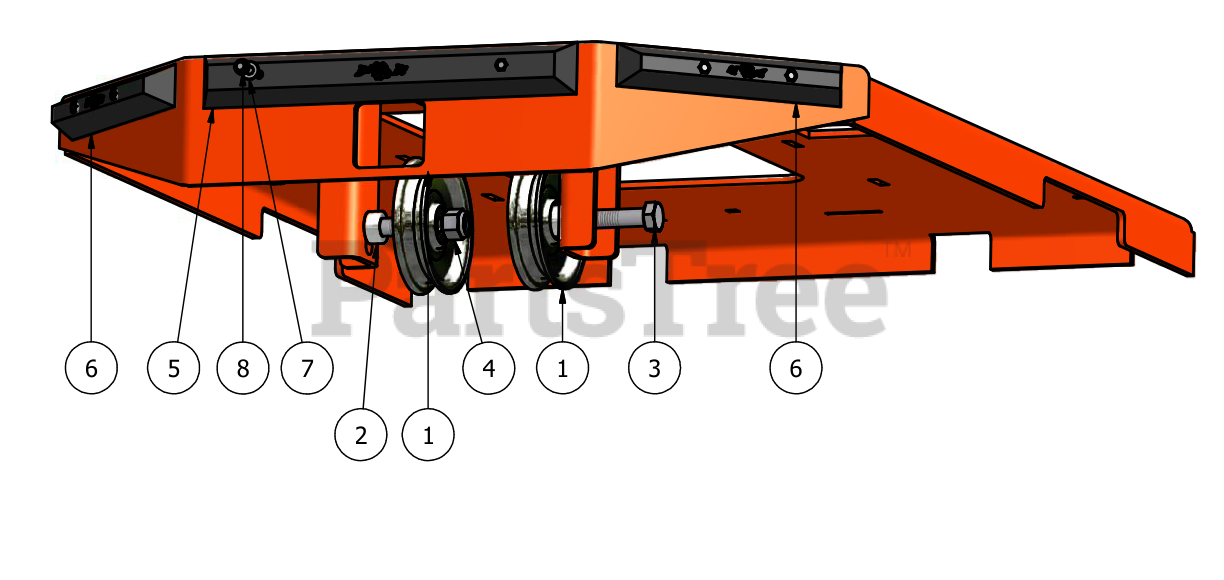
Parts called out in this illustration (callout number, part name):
1	5" V Idler Pulley
2	5/8" x 1/2" Collar Spacer
3	5/8" x 2 1/2" Bolt
4	5/8" Nylock Nut
5	14" Bumper
7	1/4" Flat Washer
8	1/4" x 1 1/2" Self Tapping Screw
